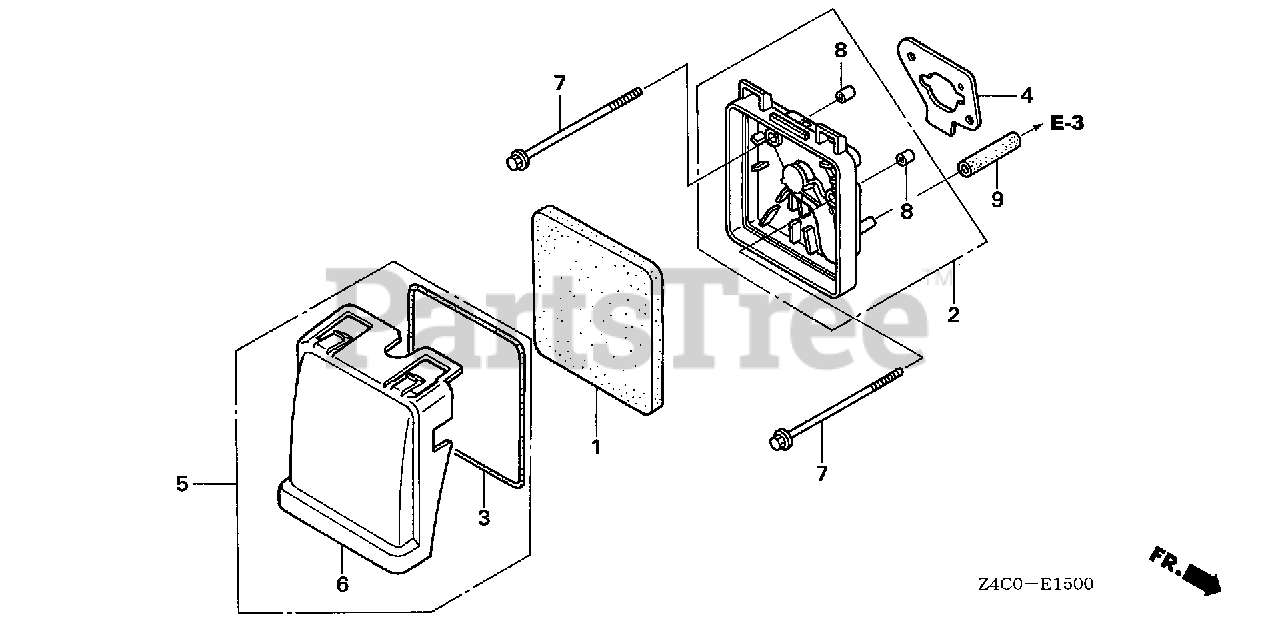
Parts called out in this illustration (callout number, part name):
1	ELEMENT, AIR CLEANER
2	HOUSING, AIR CLEANER
3	SEAL, AIR CLEANER
4	GASKET, AIR CLEANER
5	COVER, AIR CLEANER
6	COVER, AIR CLEANER
7	BOLT, FLANGE (5X75)
8	COLLAR, AIR CLEANER
9	BULK HOSE, VACUUM (7X3000) (7X550)
